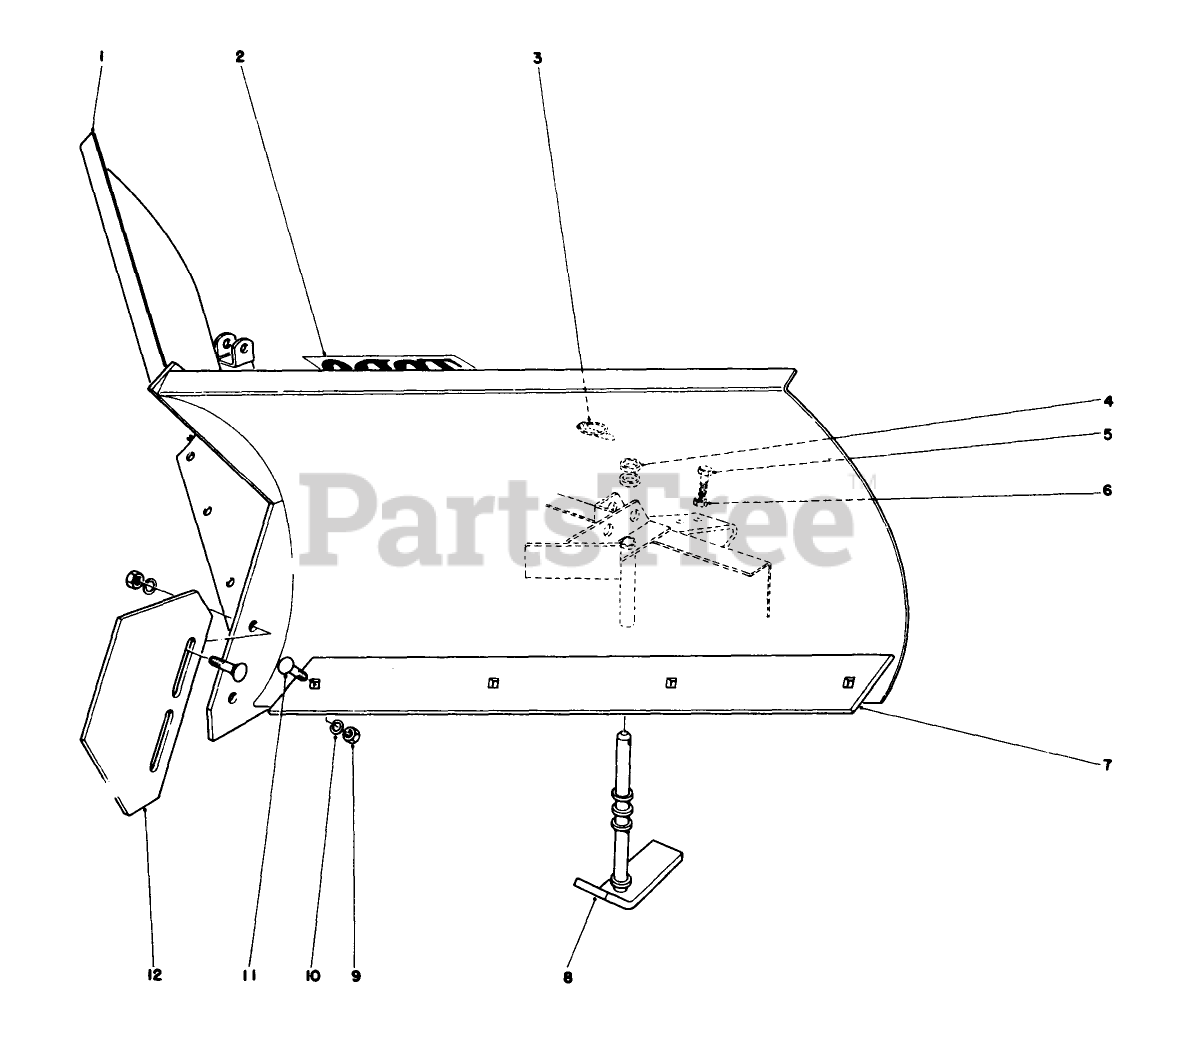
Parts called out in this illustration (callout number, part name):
1	V-Plow
2	Decal
3	PIN-LYNCH
4	SPACER TUBE B
5	SCREW-HH
6	NUT-JAM
7	Blade-Scraper
8	Skid
9	NUT-HH
10	WASHER-LOCK
11	SCREW-CARR
12	Nose Skid
